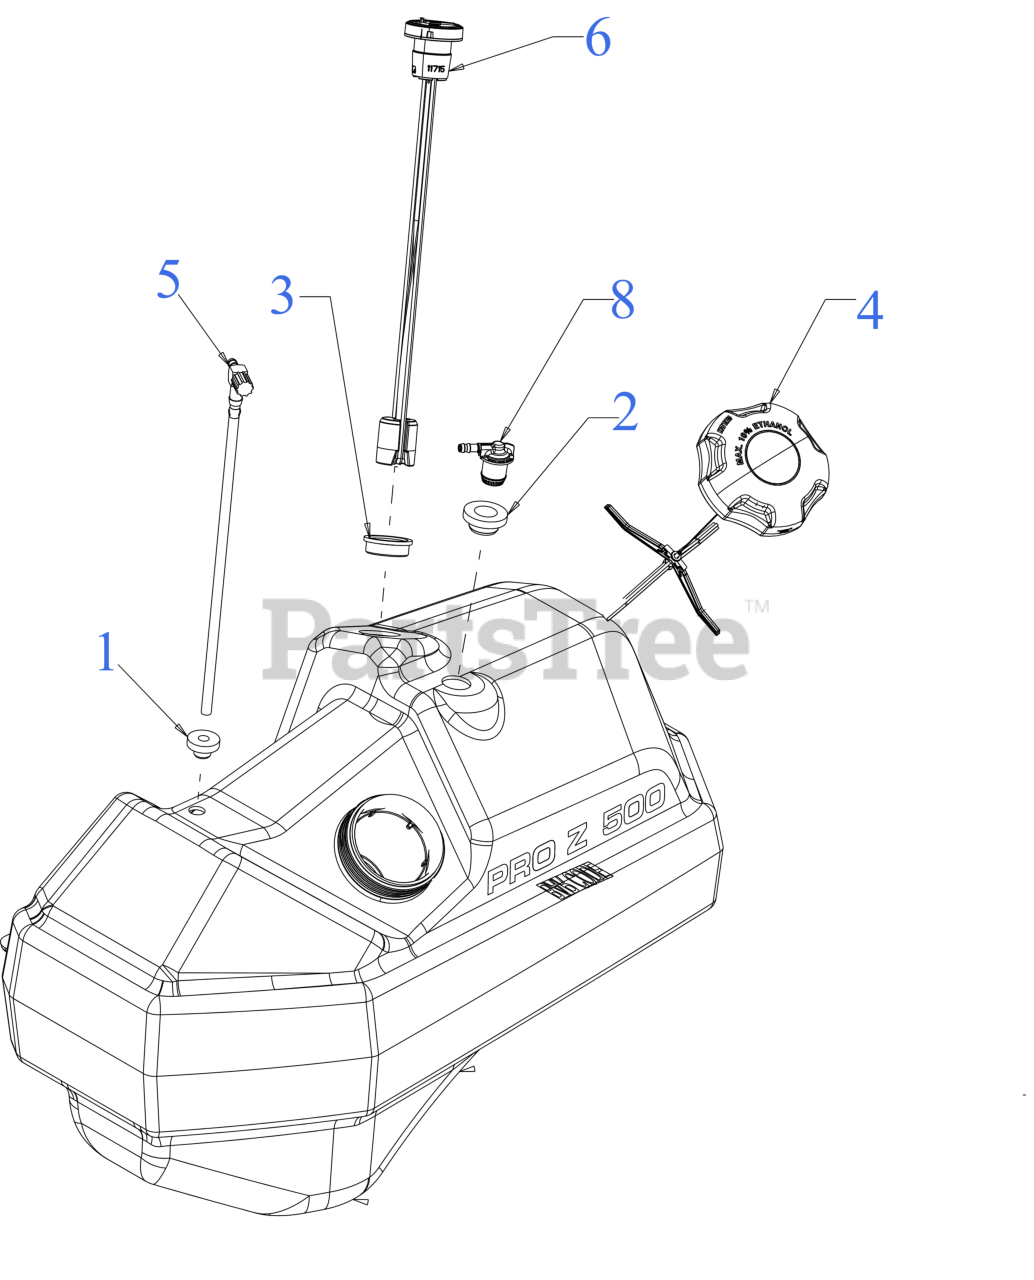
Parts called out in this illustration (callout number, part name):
1	GROMMET-FUEL TANK
2	GROMMET .755 x .955 x .55
3	GROMMET 1.174X1.400X0.505
4	FUEL CAP - 3.50" ONE WAY VENT
5	FUEL PICKUP VALVE
6	FUEL GAUGE
8	FUEL VENT FITTING
